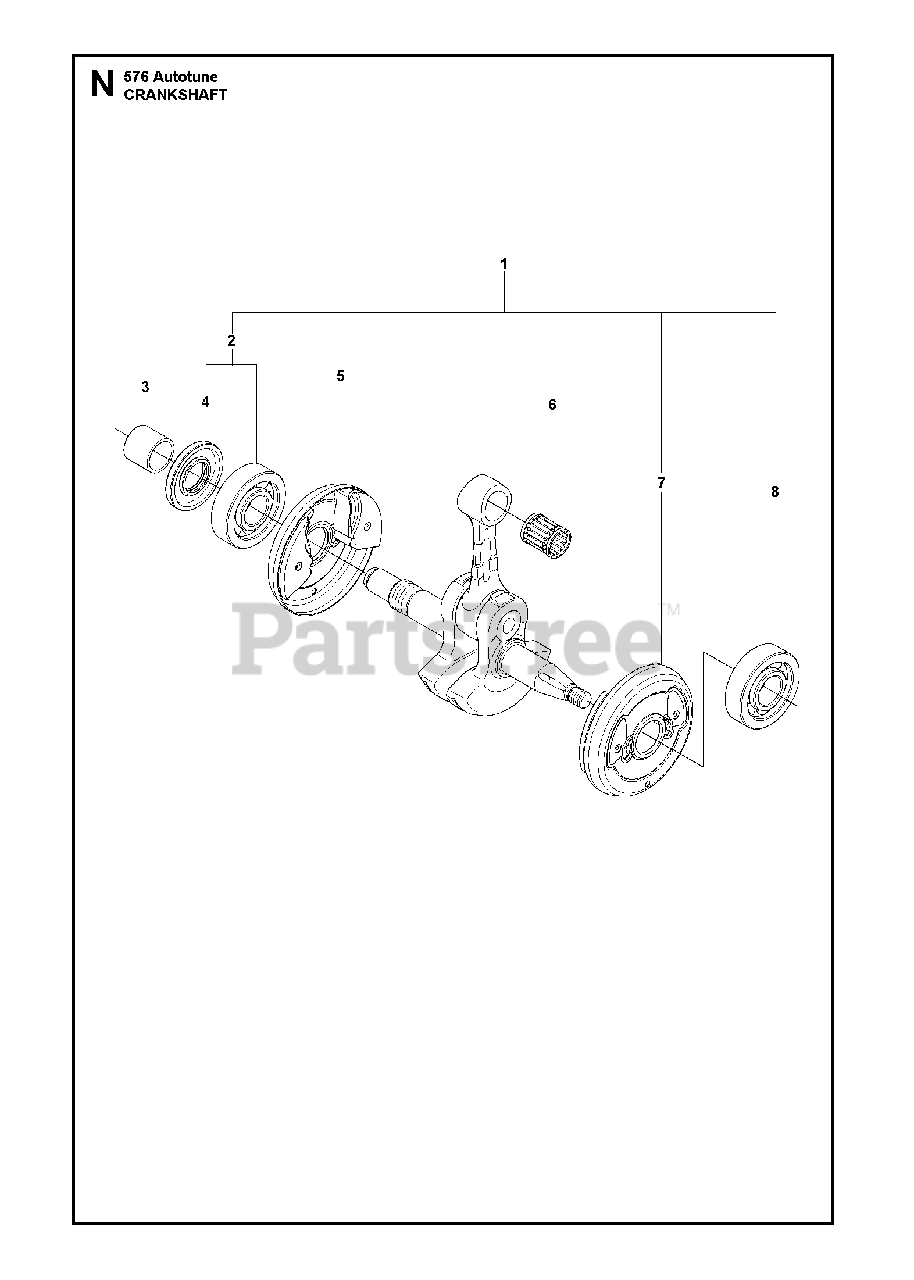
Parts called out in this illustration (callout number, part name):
1	RP CRANKSHAFT ASSY
2	%BALL BEARING
4	RADIAL SEAL
5	CUP
6	SUPPORT BUSHING
7	CUP
8	BALL BEARING
